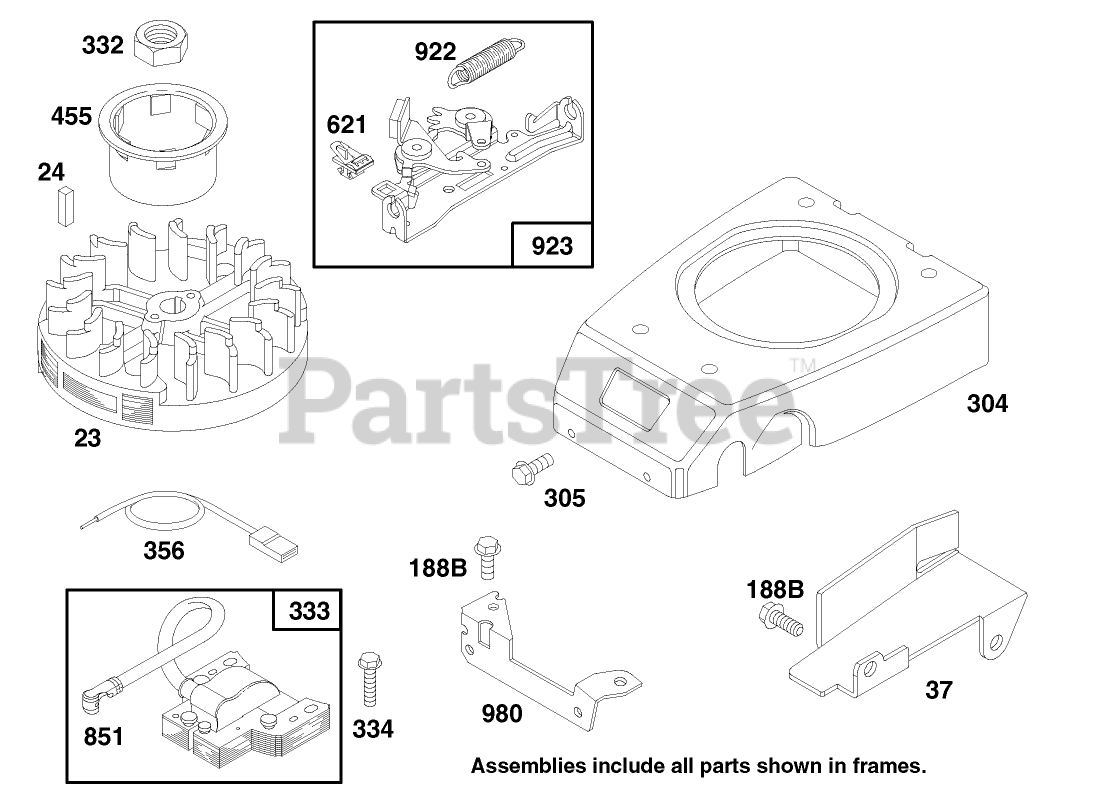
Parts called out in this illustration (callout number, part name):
24	KEY - FLYWHEEL
37	GUARD - FLYWHEEL
188	SCREW - SEM
305	SCREW - HEX HEAD
332	NUT - HEXAGON
356	WIRE - GROUND
455	CUP - STARTER
621	STOP SWITCH
980	BRACKET-BLOWER HSG
